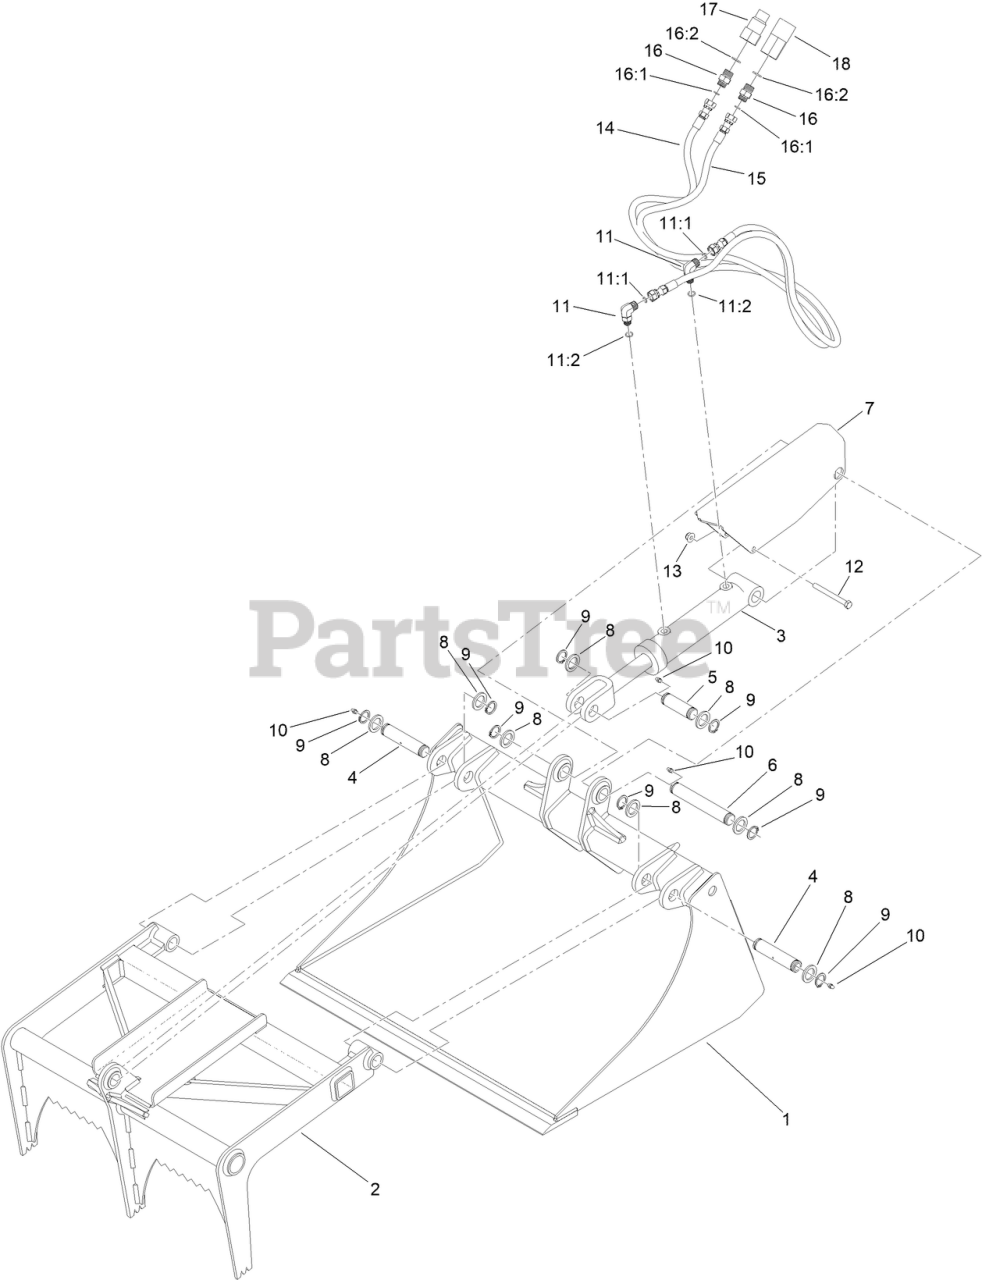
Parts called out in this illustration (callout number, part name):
1	BUCKET-GRAPPLE, 30"
2	JAW-GRAPPLE, 30"
3	CYLINDER-HYD
4	PIN-PIVOT
5	PIN-PIVOT
6	PIN-HINGE
7	GUARD - GRPL BUCKET
8	SPACER-HARDENED
9	RING-RETAINING
10	FITTING-ZERK
11	FITTING-ELBOW, 90 DEG
11:1	O-RING
11:2	O-RING
12	SCREW-HH
13	NUT-HF, NI
14	HYD HOSE ASM
15	HYD HOSE ASM
16	FITTING-STRAIGHT
16:1	O-RING
16:2	O-RING
17	COUPLER-MALE
18	COUPLER-FEMALE
